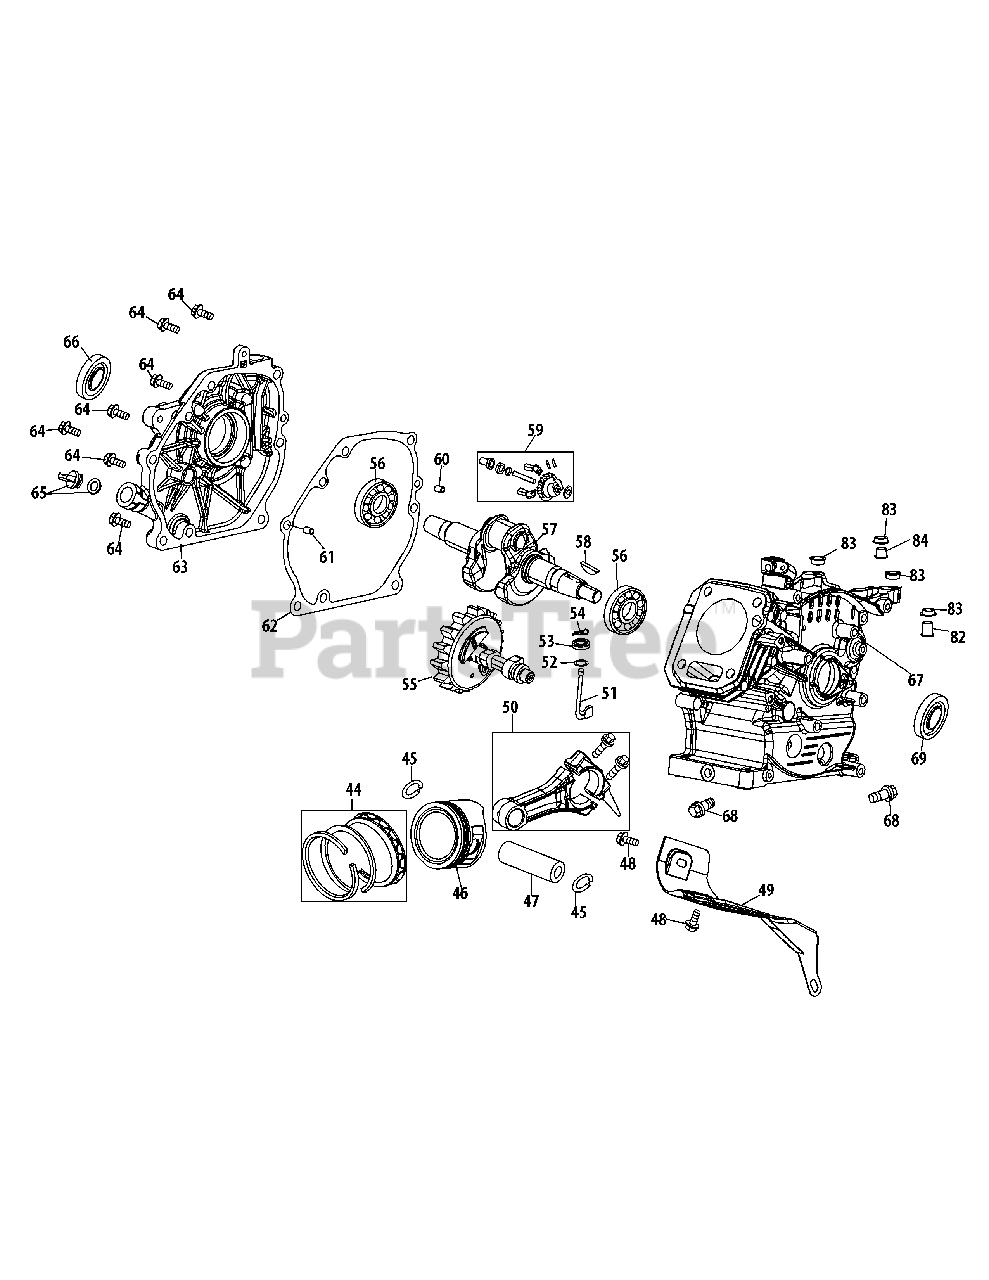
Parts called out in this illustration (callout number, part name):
44	Piston Ring Set
45	Piston Pin Snap Ring
47	Piston Pin
48	Bolt M6×12
49	Air Shield
50	Connecting Rod Assembly
51	Governor Arm Shaft
52	Washer, 5.2×1.9
53	Governor Seal
54	Cotter Pin
55	Camshaft Assy.
56	Radial Ball Bearing, 6205
57	Crankshaft Assembly
58	Woodruff Key
59	Governor Gear/Shaft Asm
60	Dowel Pin, 7×14
61	Dowel Pin, 9×14
62	Crankcase Cover Gasket
63	Cover Comp, Left Crankcase
64	Bolt M8×32
65	Oil Fill Plug Assembly
66	Oil Seal, 25×41.25×6
67	Crankcase
68	Oil Drain Plug
69	Oil Seal , 25×41.25×6
82	Isolator Bushing
83	Rubber Isolation Mount
84	Isolator Bushing
